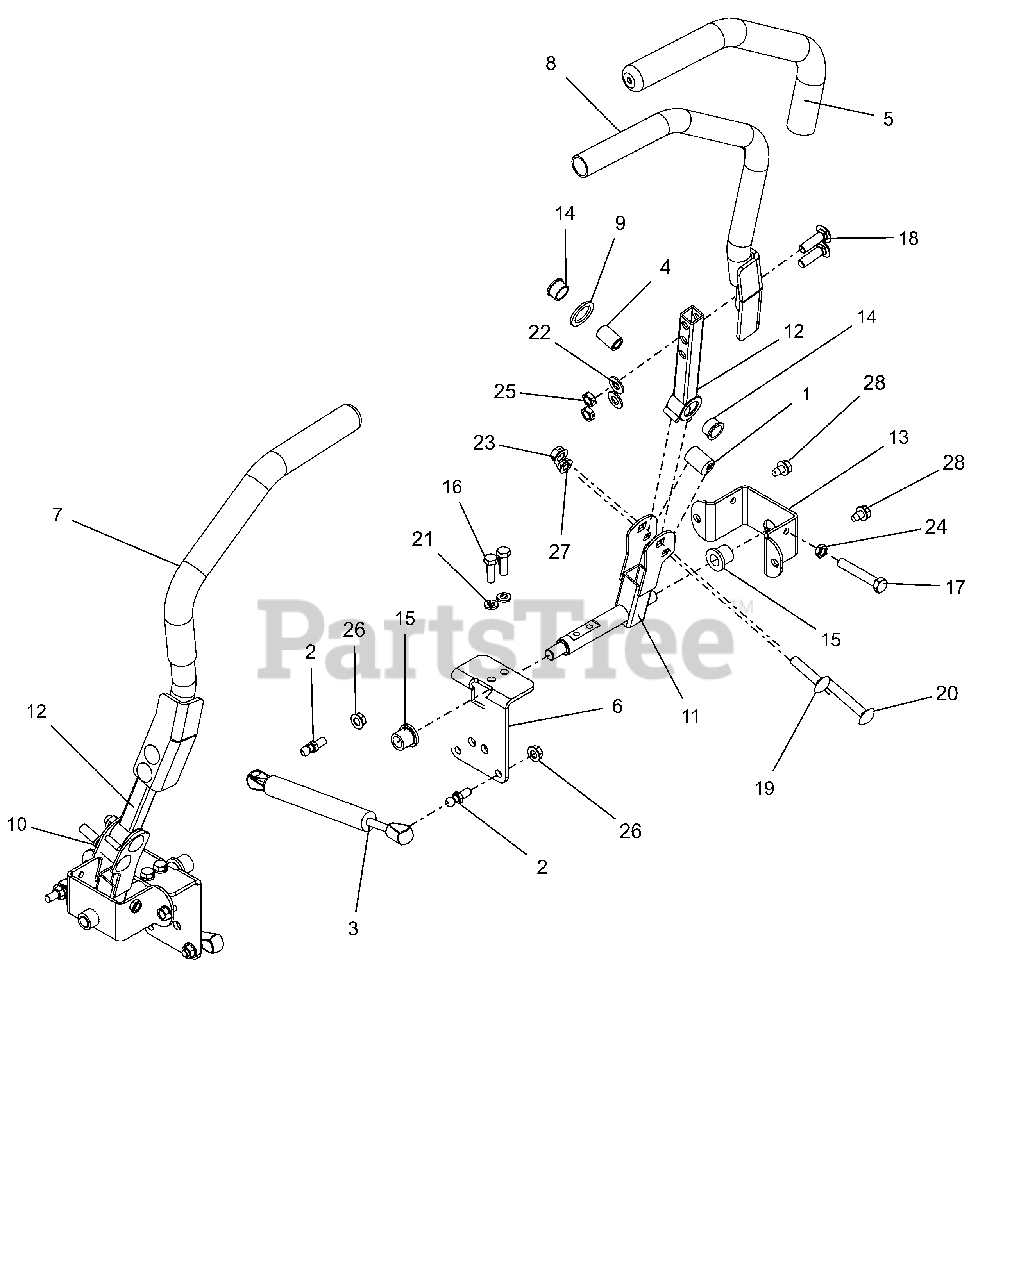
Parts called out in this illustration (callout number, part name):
1	BSHG,ECCEN .328X.750X1.01 PM
2	STUD- BALL
3	DAMPER, STABILUS
4	SPACER, .375X.625X.970 (PM)
5	GRIP, HANDLEBAR 15" FOAM
6	BRKT, STEEERING
7	WLDMT, STEERING HANDLE RH
8	WLDMT, STEERING HANDLE LH
9	WASHER, FRICTION .875X1.25X.10
10	WLDMT,STEERING ARM LOWER RIGHT
11	WLDMT,STEERING ARM LOWER LEFT
12	WLDMT, UPPER CONTROL ARM
13	BRKT, STEERING
14	BSHG-FLG, .625X.75X.450X.875
15	BSHG-FLG .515X.750X.745X1.00NY
16	BLT-HEX .31-18X1.00 GR8 YWZC
17	@BLT-HEX .38-16X2.25 GR5 YWZC
18	BLT,RHSSN-.375X1.25 G5 RIE5230
19	BLT,RHSSN-.375X1.75 G5 RIE5230
20	BLT,RHSSN-.312X1.75 G5 RIE5230
21	@WSHR-LK .31X.078 REG YWZC
22	@WSHR-FL-STL.406X.812X.065 YWZ
23	NUT-LK-CTR-FLG .38-16 YWZC
24	NUT- JAM .312-18 YWZC
25	@NUT-LK-CTR-JAM .375-16 YWZC
26	@NUT-LK-TOP-FLG .31-18 YWZC
27	@NUT-LK-NYL-FLG .31-18 YWZC
28	@SCR-TAP .31-18X.50 HWH TR YWZ
